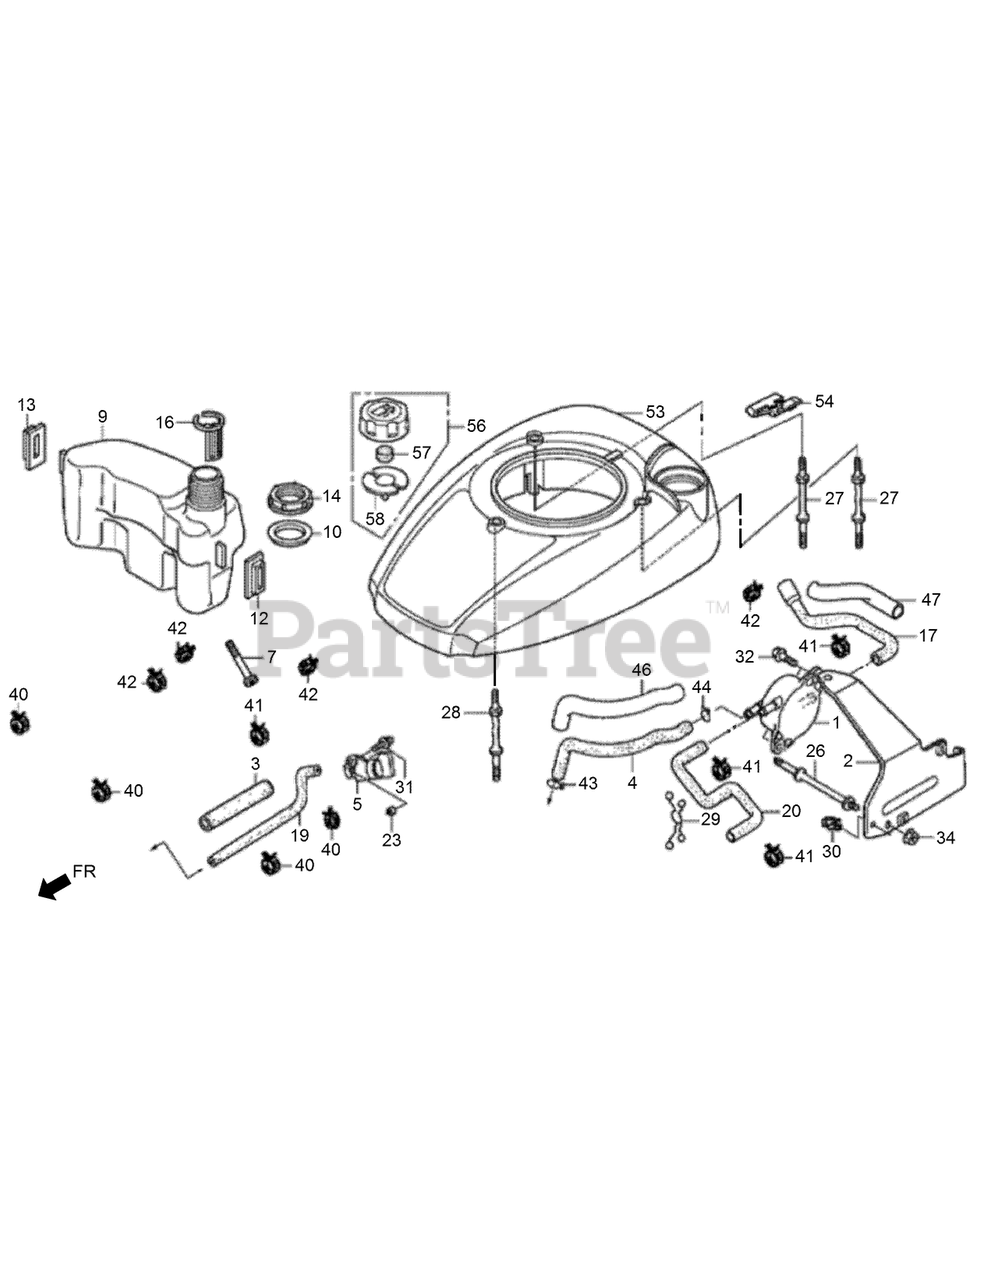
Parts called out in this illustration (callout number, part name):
1	PUMP ASM-FUEL
2	STAY-FUEL PUMP
3	RUBBER-SUPPORTER
4	TUBE-DIAPHRAGM
5	COCK ASM-FUEL
7	STRAINER-FUEL
9	TANK-FUEL
10	SEAL-FUEL FILLER NECK
12	RUBBER A-TANK MOUNTING
13	RUBBER B-TANK MOUNTING
14	NUT-TANK MOUNTING
16	GAUGE-FUEL LEVEL
17	TUBE-FUEL TANK
19	TUBE-FUEL
20	TUBE B-FUEL
23	COLLAR-FUEL COCK
26	BOLT-STUD
27	BOLT-STUD
28	BOLT-STUD
29	CLIP-PURSE LOCK
30	CLIP-WIRE HARNESS
31	SCREW-WASHER-5X10
32	SCREW-WASHER-5X14
34	NUT-FLANGE-6MM
40	CLAMP-TUBE
41	CLAMP-TUBE
42	CLAMP-TUBE
43	CLIP-TUBE
44	CLIP-TUBE
46	TUBE-VINYL-9X11X210
47	TUBE-VINYL-13X15X90
53	COVER-FAN (NH1)
54	CLIP-TANK MOUNTING (NH1)
56	CAP ASM-FUEL TANK
57	SPONGE-FUEL CAP BREATHER
58	PACKING-FUEL CAP
